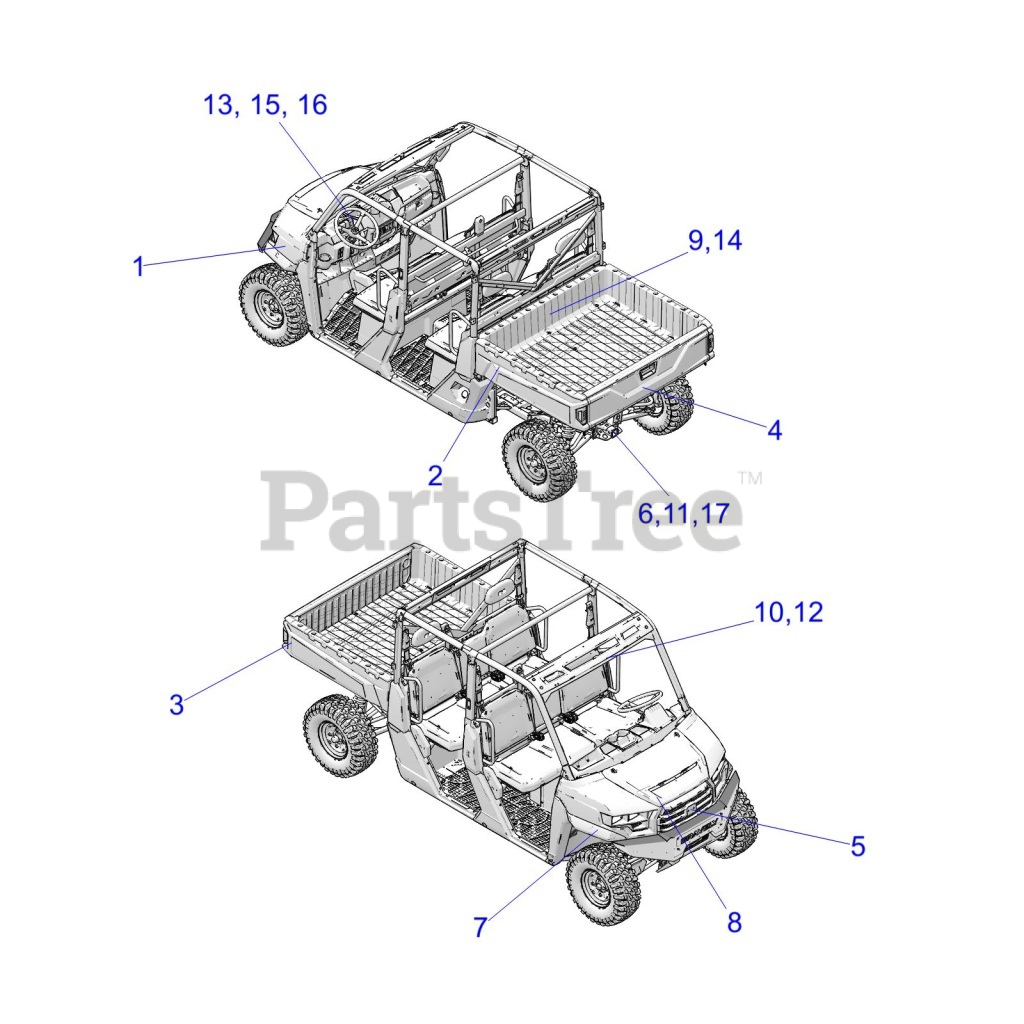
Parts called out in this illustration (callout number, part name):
1	DECAL-FENDER,SIDE,ARNS,LH
1	DECAL-FENDER,SIDE,ARNS,RH
4	DECAL-TAILGATE,ARNS,CNTR,POLY
4	DECAL-TAILGATE,ARNS,POLY,LH
6	DECAL-WARN,HOT/HITCH,2500LBS
7	DECAL, REFLECTOR AMBER LH
8	DECAL, REFLECTOR AMBER RH
9	DECAL-COOLANT
10	DECAL-WARN,NEVER CARRY FUEL
11	DECAL-WARN,PROPER USE,6 OC.
12	DECAL-TIE DOWN,LH
13	DECAL-WARN,SEATBLT/COML/RIDERS
14	DECAL-START,STOP
15	DECAL-WARN,PASS/TIRE,ARNS
16	DECAL-CAUTION,SHIFT
17	DECAL-WARN,PAYLOAD,ARNS
18	DECAL, BELT, CAUTION/CHECK
18	DECAL-TIE DOWN,RH
